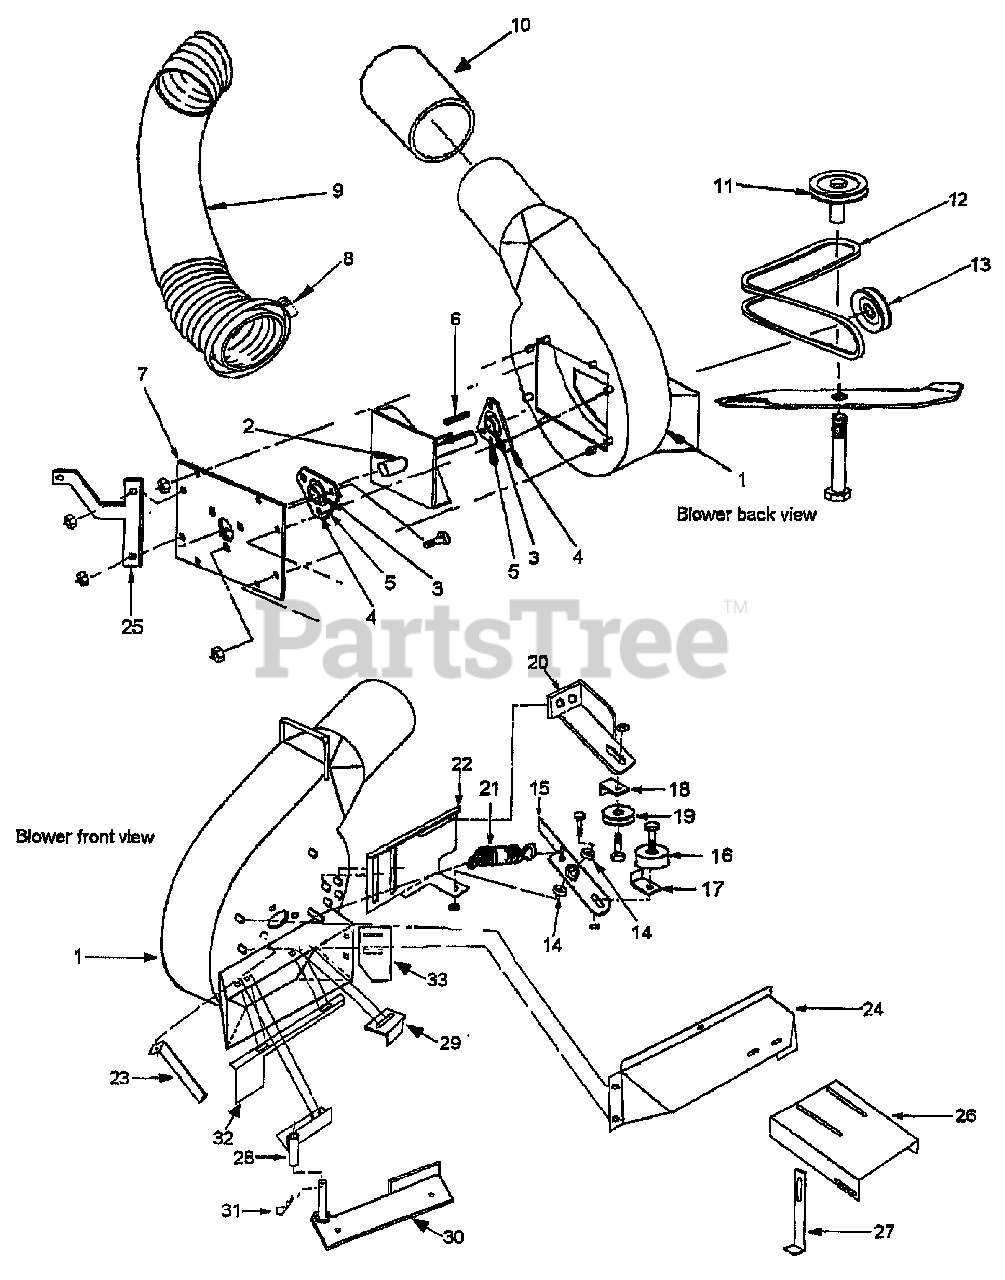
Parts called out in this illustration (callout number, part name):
1	BLOWER CANISTER UNIVERSAL
3	FAN BEARING w/collar for blower back side
4	BEARING FLANGETTE WITH GREASE ZERK
5	BEARING FLANGETTE
6	MACHINERY KEY 1/4" x 1"
7	BLOWER COVER PLATE
8	7" HOSE CLAMP
9	6" HOSE X 46"
10	HOSE INSERT 6"
11	DECK PULLEY - (48", 54" and 80" DECK)
12	BELT INSTA POWER A56
13	BLOWER DRIVE PULLEY 3.5
14	IDLER ARM BEARING
15	IDLER ARM
16	FLAT IDLER PULLEY 3.25"
17	FLAT IDLER PULLEY BRACKET
18	V-IDLER PULLEY BRACKET
19	V-IDLER PULLEY 3.5"
20	V PULLEY BRACKET
21	IDLER SPRING
22	BLOWER PULLEY BRACKET
23	FAN PULLEY BELT BRACKET
24	BLOWER BELT COVER
25	PULLEY BRACKET SUPPORT
26	BELT GUARD
27	BELT GUARD LEG
28	BLOWER MOUNT FRONT
29	BLOWER SUPPORT BRACKET
30	BLOWER MOUNT DECK
31	HAIR SPRING COTTER # 6
32	BLOWER TAB
33	BLOWER BLOCKING PLATE
